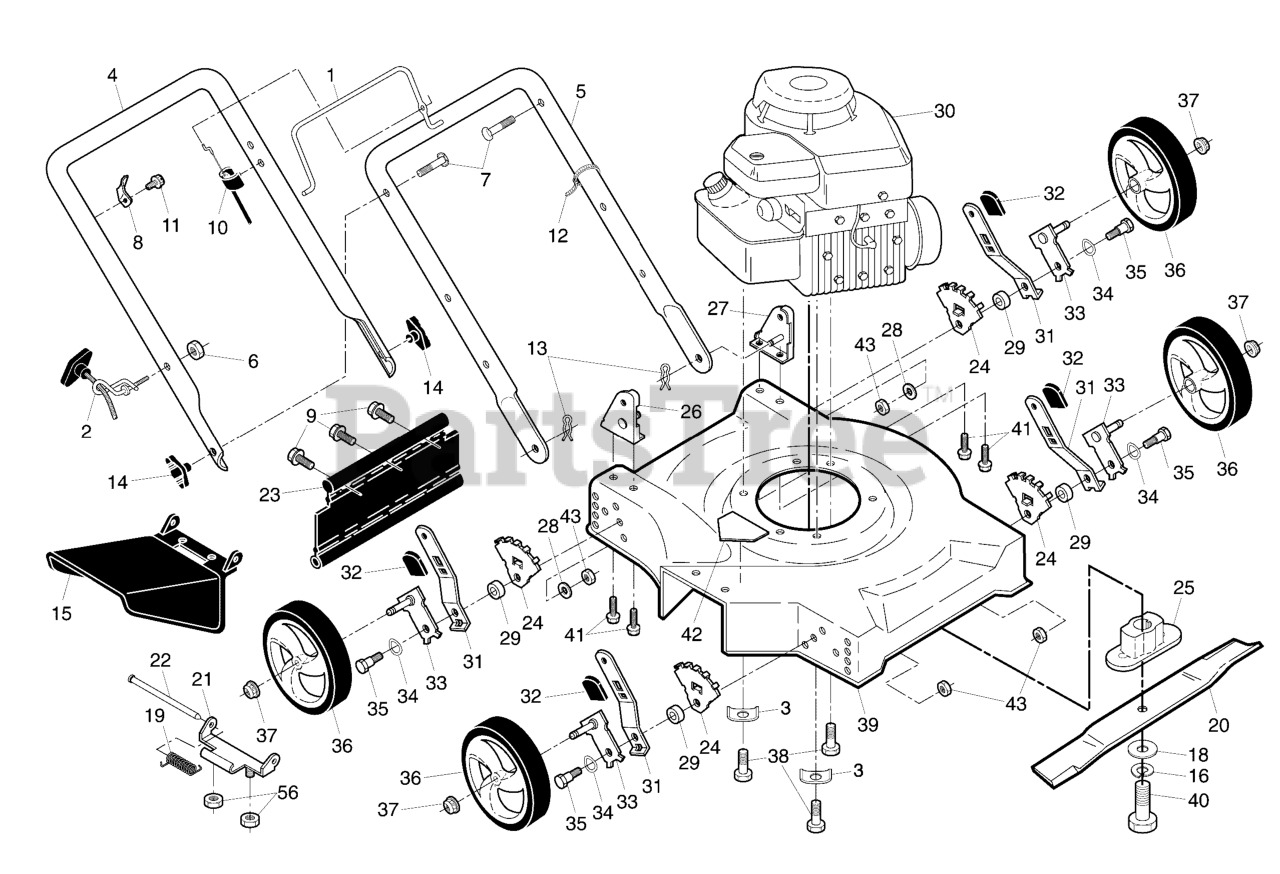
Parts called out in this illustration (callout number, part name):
1	Control Bar
2	Rope Guide
3	Engine Washer
4	Upper Handle
5	Lower Handle
6	Nut, Hex
7	Handle Bolt 5/16-18 x 1-3/4
8	Up-Stop Bracket
9	Hex Washer Head Screw #10-
10	Engine Zone Control Cable
12	Wire Tie
13	Hairpin Cotter
14	Knob, Handle
15	Discharge Guard
16	Helical Lock Washer 3/8
18	Hardened Washer
19	Torsion Spring
20	Blade, 20"
21	Hinge Deflector
22	Hinge Rod
23	Rear Deflector
24	Wheel Adjusting Bracket
25	Blade Adapter
26	Handle Bracket Assembly, RH
27	Handle Bracket Assembly, LH
28	** Washer, Flat
29	Spacer
30	* Engine, Briggs & Stratton
31	Selector Spring
32	Selector Knob
33	Axle Arm Assembly
34	Belleville Washer
35	Shoulder Bolt
36	Wheel and Tire Assembly
37	Nut, Hex
38	Hex Head Thread Rolling Screw 3/8-16 x 1-1/8
39	Lawn Mower Housing
40	Hex Head Screw 3/8-24 x 1-3/8 Grade 8
41	Thread Cutting Screw 5/16-18 x 3/4
42	Danger Decal
43	Locknut, Hex 5/16-18
56	Locknut, Hex 1/4-20
